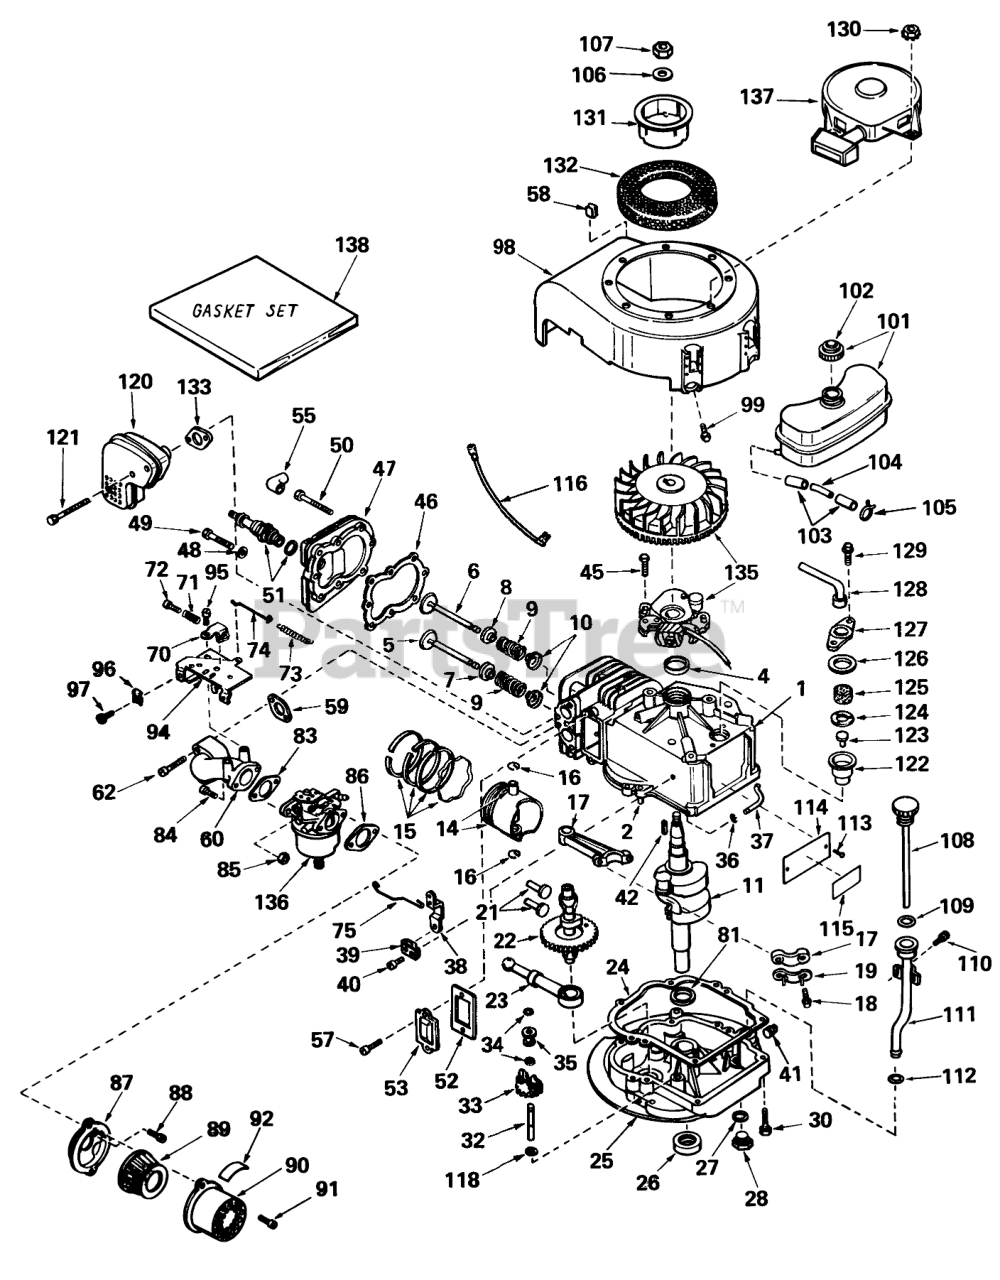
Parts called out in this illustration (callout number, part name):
1	Cylinder Assy. (Incl. Nos. 2 & 4)
2	Pin-Dowel
4	Seal-Oil
5	Valve, Intake (Standard) (Incl. Nos. 7, 9 & 10)
5	Valve, Intake (1/32" Oversize) (Incl. Nos. 7, 9 & 10)
6	Valve, Exhaust (Standard) (Incl. Nos. 8, 9 & 10)
6	Valve, Exhaust (1/32" Oversize) (Incl. Nos. 8, 9 & 10)
7	Cap-Upper Valve Spring
8	Cap, Upper Valve Spg (Exhaust)
9	Spring-Valve
10	Cap-Valve, Spring
11	Crankshaft
14	Piston & Pin Assy. (Standard) (Incl. 2 of No. 16)
14	Piston & Pin Assy. (.010 Oversize) (Incl. 2 of No. 16)
14	Piston & Pin Assy. (.020 Oversize)(Incl. 2 of No. 16)
15	Ring Set-Piston Std.
15	Ring Set-Piston .010 oversize
15	Ring Set-Piston .020 oversize
16	Ring-Retaining, Piston Pin
17	Rod Assy., Connecting (Incl. Nos. 18 & 19)
18	Connecting Rod Bolt
19	Plate Lock
21	Lifter-Valve
22	Camshaft (Compr. Release)
23	Oil Pump ASM
24	Gasket, Mounting
25	Flange Assy., Mounting (Incl. Nos. 26, 27, 28 & 32)
26	Seal-Oil
27	Gasket-Oil Drain
28	Plug, Drain
30	Screw (1/4-20 x 1-1/4)
32	Shaft-Governor
33	Gear Assy., Governor (Incl. No. 118)
34	Ring-Retaining
35	Spool-Governor
36	Washer-Flat
37	Rod, Governor (Incl. No. 36)
38	Governor Lever
39	Clamp-Lever, Governor
40	Screw
41	Plug-Pipe
42	Key Flywheel
46	Oil Fill Tube
47	Head Cylinder
49	Screw
50	Screw Hex Hd. Cap
51	Plug, Spark (J17LM or equiv.)
52	Gasket-Breather
53	Cover-Valve
55	Cover-Spark Plug
58	51004 GIL ROTARY TI
59	Gasket, Intake
60	Pipe, Intake
62	Screw, Fil. Slotted Hd.Sems
70	Brachet, Control
72	Screw, Hex Hd.
73	Spring, Governor
74	Link Governor Spring
75	Link Governor
81	Washer-Thrust
83	Gasket
84	Screw (1/4-28 x 7/8)
85	Nut and Lock Washer (1/4-28)
86	Gasket
87	Bracket
88	Screw (10-32 x 1/2)
89	Element
90	Body
94	Control Assy., Speed
95	Screw (10-24 x 9/16)
96	Conduit
97	Screw (10-32 x 3/8)
98	Housing, Blower
99	Screw (1/4-20x19/32)
101	Tank Assy., Fuel (Incl. No. 102)
102	Cap, Fuel
103	Line-Fuel (8.62)
104	Line, Fuel
105	Clamp-Line, Fuel
106	Washer-Spring
107	Hex Nut
108	Dipstick, Assy., Oil (Incl. No. 109)
110	Screw (10-32 x 1/2)
111	Tube Assy., Oil Fill
114	IDENTIFICATION PLATE
115	480B GIL SNWTHWR O/
116	SPOOL RETAINER (10-PK)
118	Washer-Flat
120	Muffler
121	Screw-Fil. Hd.
122	Body Breather Tube
123	Valve Check
124	2000A37 WIZARD ROTA
125	Element-Breather
126	Gasket-Breather
127	Cover Breather
128	Tube, Breather
129	Screw, Hex Hd. w/Conical
130	Nut and Lock Washer (1/4-28)
131	Cup, Starter
132	Screen-Starter
133	Gasket-Exhaust
135	Magneto
136	Carburetor
137	Starter, Rewind
138	Gasket Set
